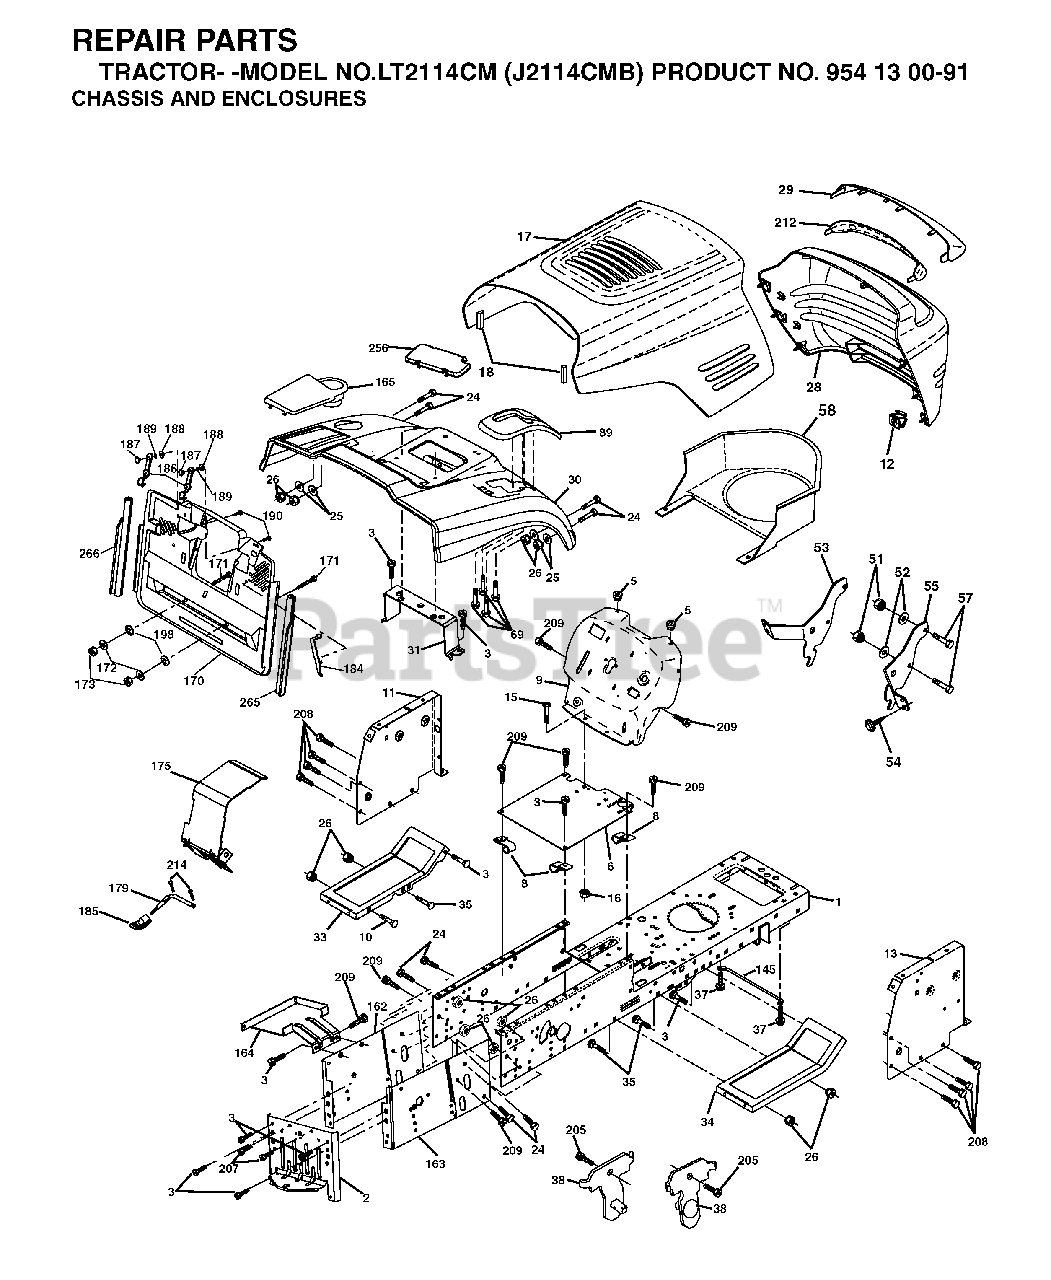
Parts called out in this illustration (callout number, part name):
1	CHASSIS
3	SCREW 3/8-16X3/4
5	BUMPER.RUBBER.HOOD
8	CLIP,INSULATOR
10	BOLT D
11	PANEL.DASH.LH.LTX
13	PANEL ASM, DASH RH
16	NUT
18	BUMPER.HOOD.LARGE.1.75"
24	BOLT
25	WASHER
26	NUT
31	BRACKET SUPPORT FENDER
35	BOLT
37	SCREW LT
51	LOCKNUT
52	WASHER
57	BOLT
58	AIR DUCT P/L/LT
69	SCREW.HI-LO.CONSOLE
145	ROD PIVOT CHASSIS/HOOD
164	SUPPORT
171	BOLT
172	WASHER
186	LATCH ASSY
187	WELDNUT
189	LOCKWASHER
190	SCREW
205	SCREW LT
207	SCREW 5/16-18X1/2"
208	SCREW 3/8-16X1/2
209	SCREW, 3/8-16X3/4
214	RETAINER M
